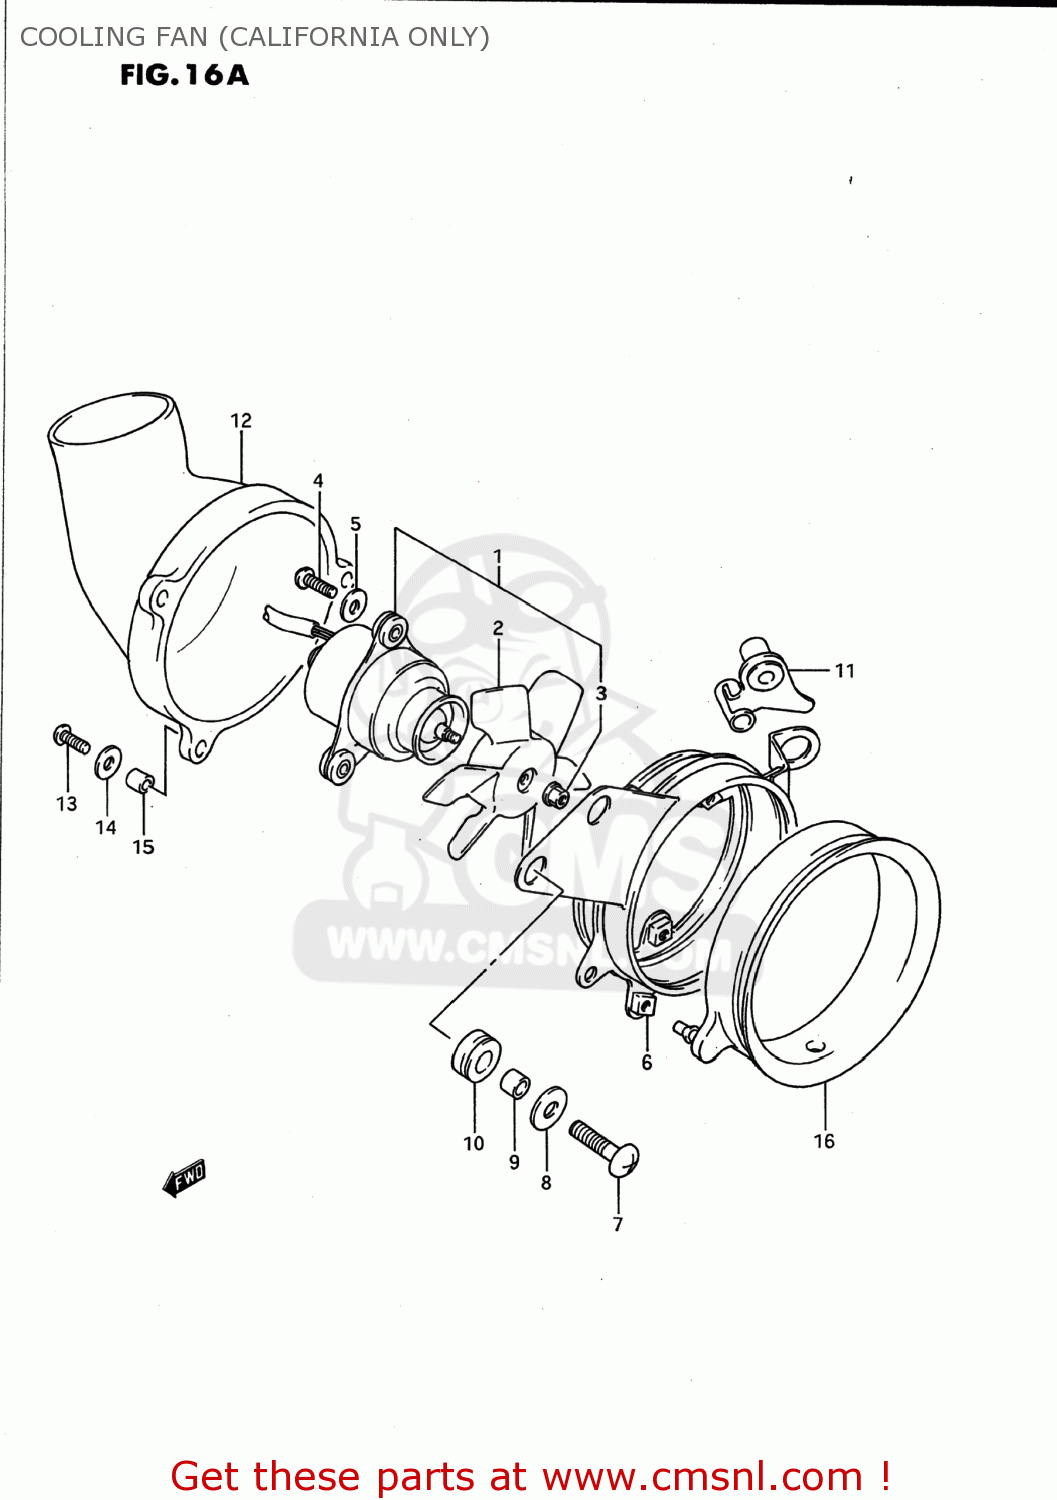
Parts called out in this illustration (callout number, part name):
1	FAN ASSY,COOLING
2	FAN
3	NUT
4	SCREW
5	WASHER (4.3X13X0.80)
6	SHROUD,FAN
7	SCREW
8	WASHER(6.5X18X1)
9	SPACER(9.2X9X6.5)
10	CUSHION
11	BRACKET,FAN SHROUD
12	DUCT,FAN COOLING NO.1
13	SCREW
14	WASHER (4.3X13X0.80)
15	SPACER (4.5X6.5X5)
16	DUCT,FAN COOLING NO.2
